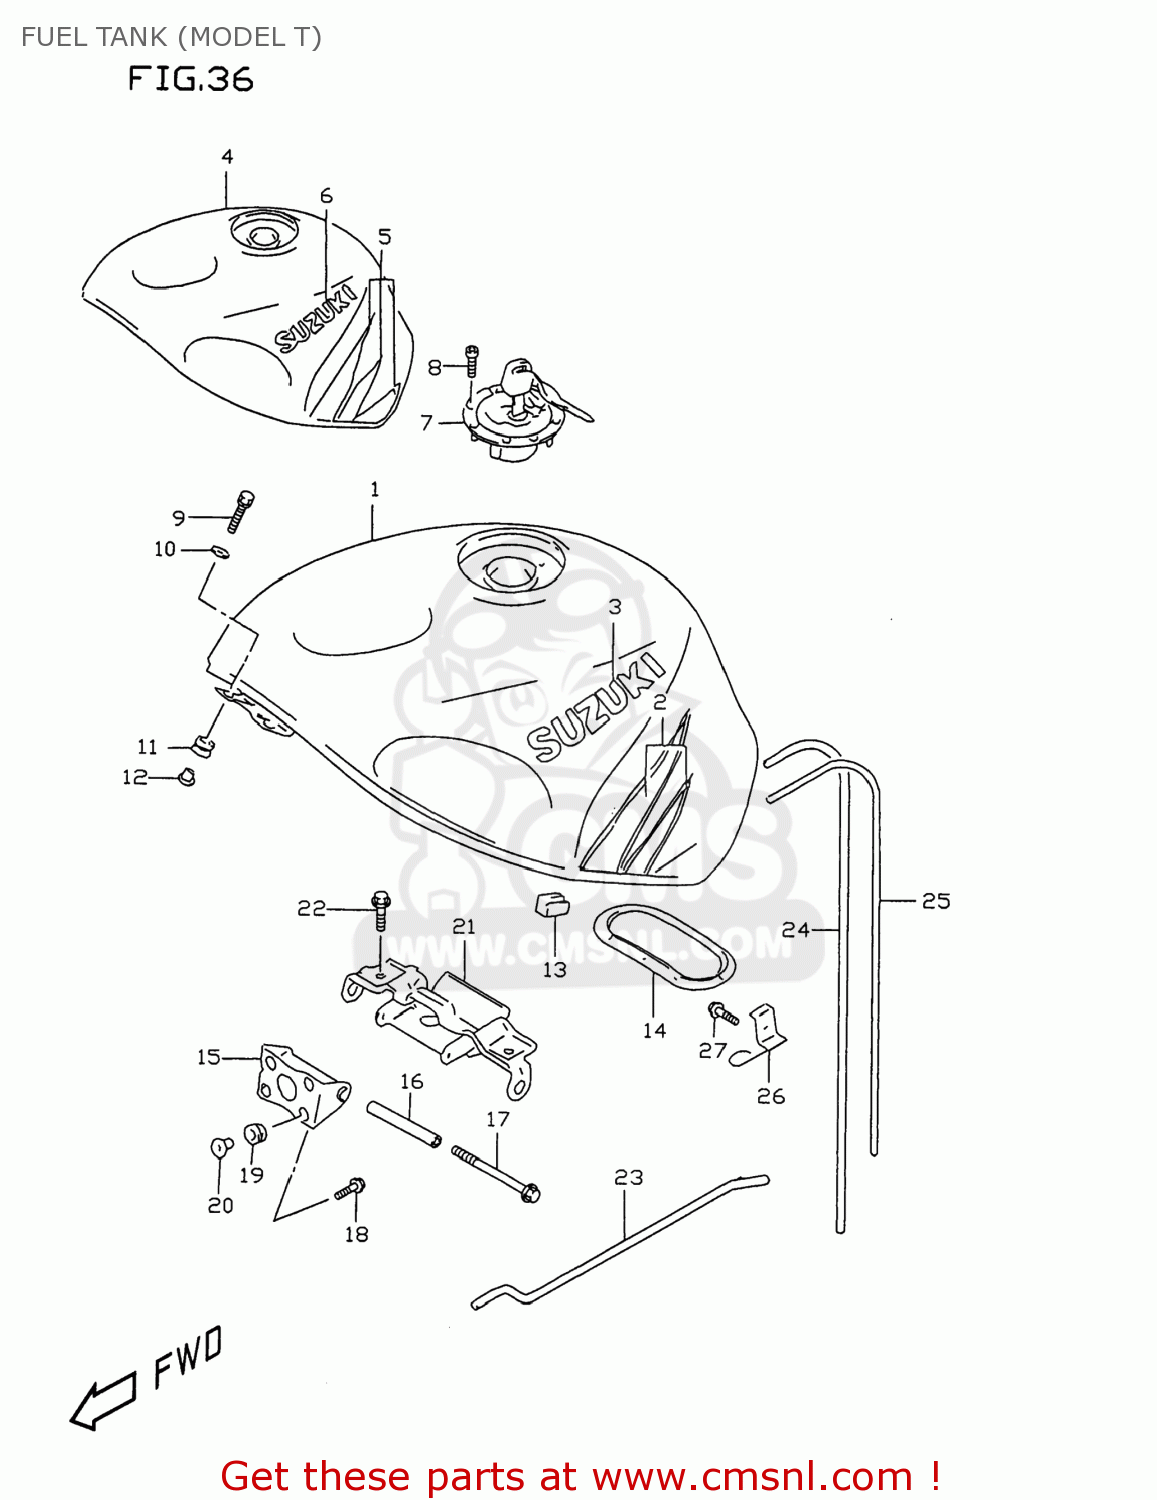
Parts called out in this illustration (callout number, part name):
1	TANK ASSY,FUEL
2	TAPE SET,FUEL TANK
3	EMBLEM,FUEL TANK
4	TANK ASSY,FUEL
5	TAPE SET,FUEL TANK
6	EMBLEM,FUEL TANK
7	CAP SET,FUEL TANK
8	BOLT(5X20)
9	SCREW(6X25)
10	WASHER
11	CUSHION
12	WASHER
13	CUSHION COMP,FUEL TANK
14	PACKING SET,FUEL PUMP (NAS)
14A	BOLT,FUEL PUMP
14B	PLATE,FUEL PUMP GASKET
15	BRACKET COMP,FUEL TANK
16	SPACER,FUEL TANK,REAR
17	BOLT
18	BOLT 6X20,WITH PLAIN WASHER
19	CUSHION
20	WASHER
21	BRACKET,FUEL TANK NO.2
22	BOLT
23	STAY,FUEL TANK
24	HOSE(5X8.2X600)
25	HOSE(7X10.2X600)
26	GUIDE COMP,DRAIN HOSE
27	BOLT
